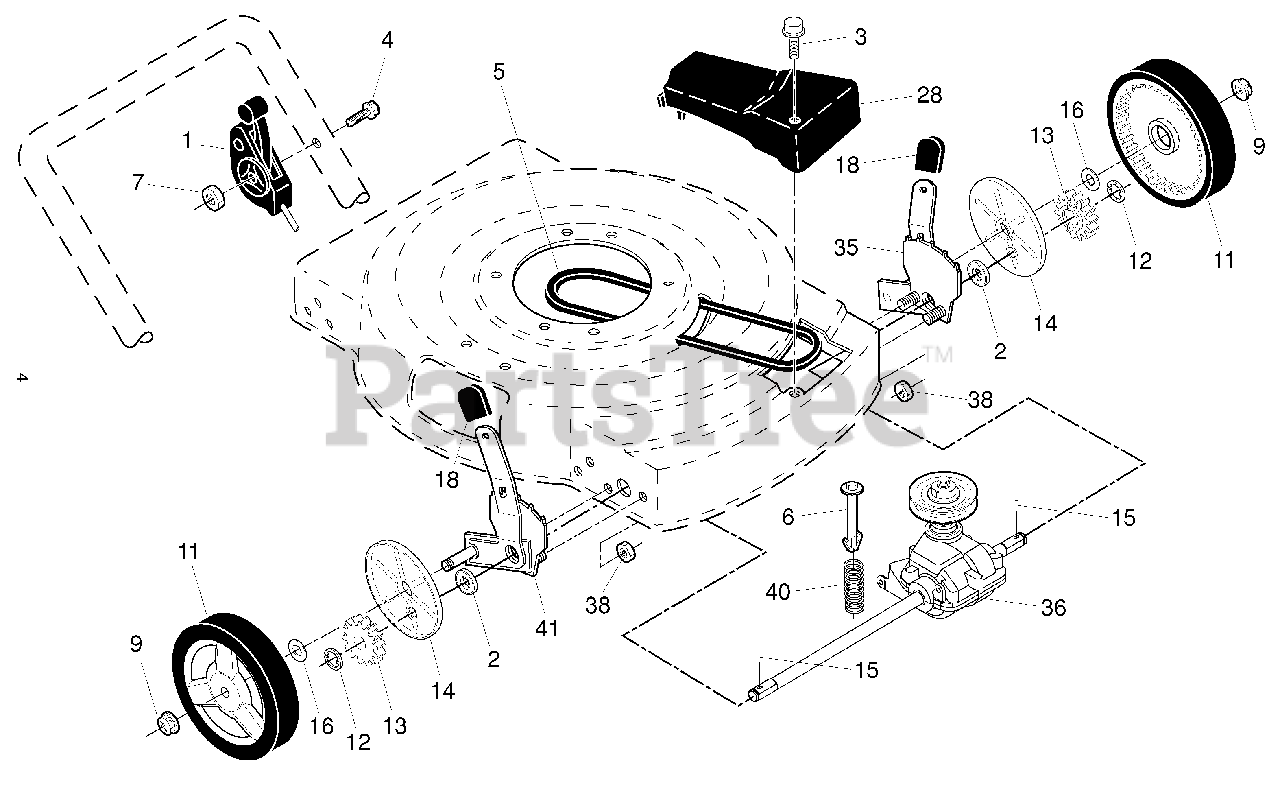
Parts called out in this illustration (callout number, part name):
1	Drive Control Assembly
2	Bearing, Wheel Adjuster
3	Screw, Tapping, Pan Head #10-24 x 2-3/4
4	Screw, Machine, Pan Head 1/4-20 x 2-3/16
5	V-Belt
6	Bolt, Hex Head 1/4-20 x 2
9	Locknut, Hex
11	Wheel & Tire Assembly
14	Dust Cover
15	Pawl, Drive
18	Knob, Selector
28	Drive Cover
35	Kit, Wheel Adjuster, LH
36	Gear Case Assembly, Complete
38	Locknut, Hex
41	Kit, Wheel Adjuster, RH
